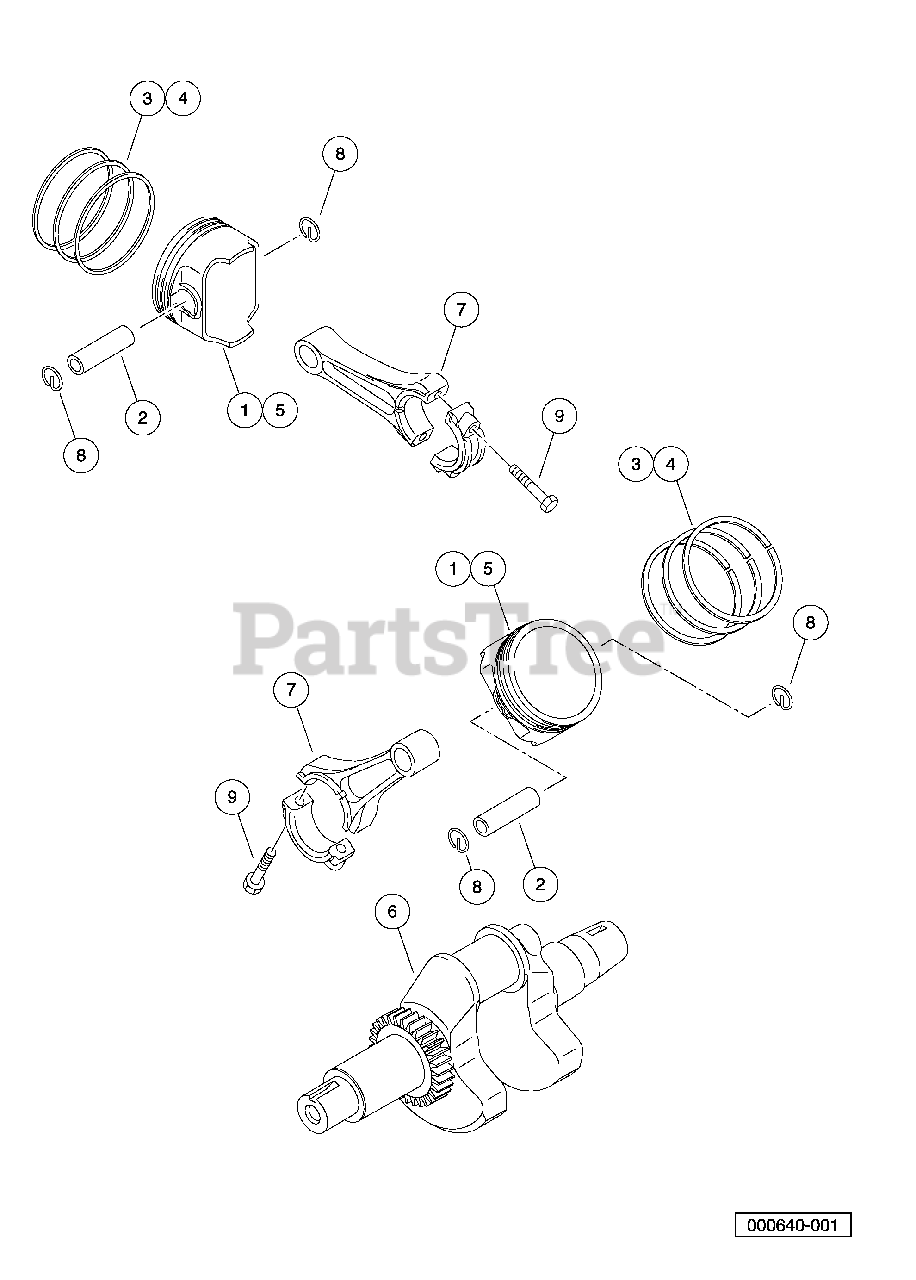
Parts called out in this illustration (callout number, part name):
1	Piston, Engine, Right, Fh
2	Pin, Piston, Engine, Fh
3	Ring, Set, Piston, Fh
4	Ring, Set, Piston L, 0.50, Fh
5	Piston, Engine L, 0.50, Fh
6	Crankshaft, Comp, Fh
7	Kit, Rod, Connecting, Fh
8	Ring, Snap, Pin, Piston, Fh
9	Bolt, Flg, M6 X 1.00 X 35
